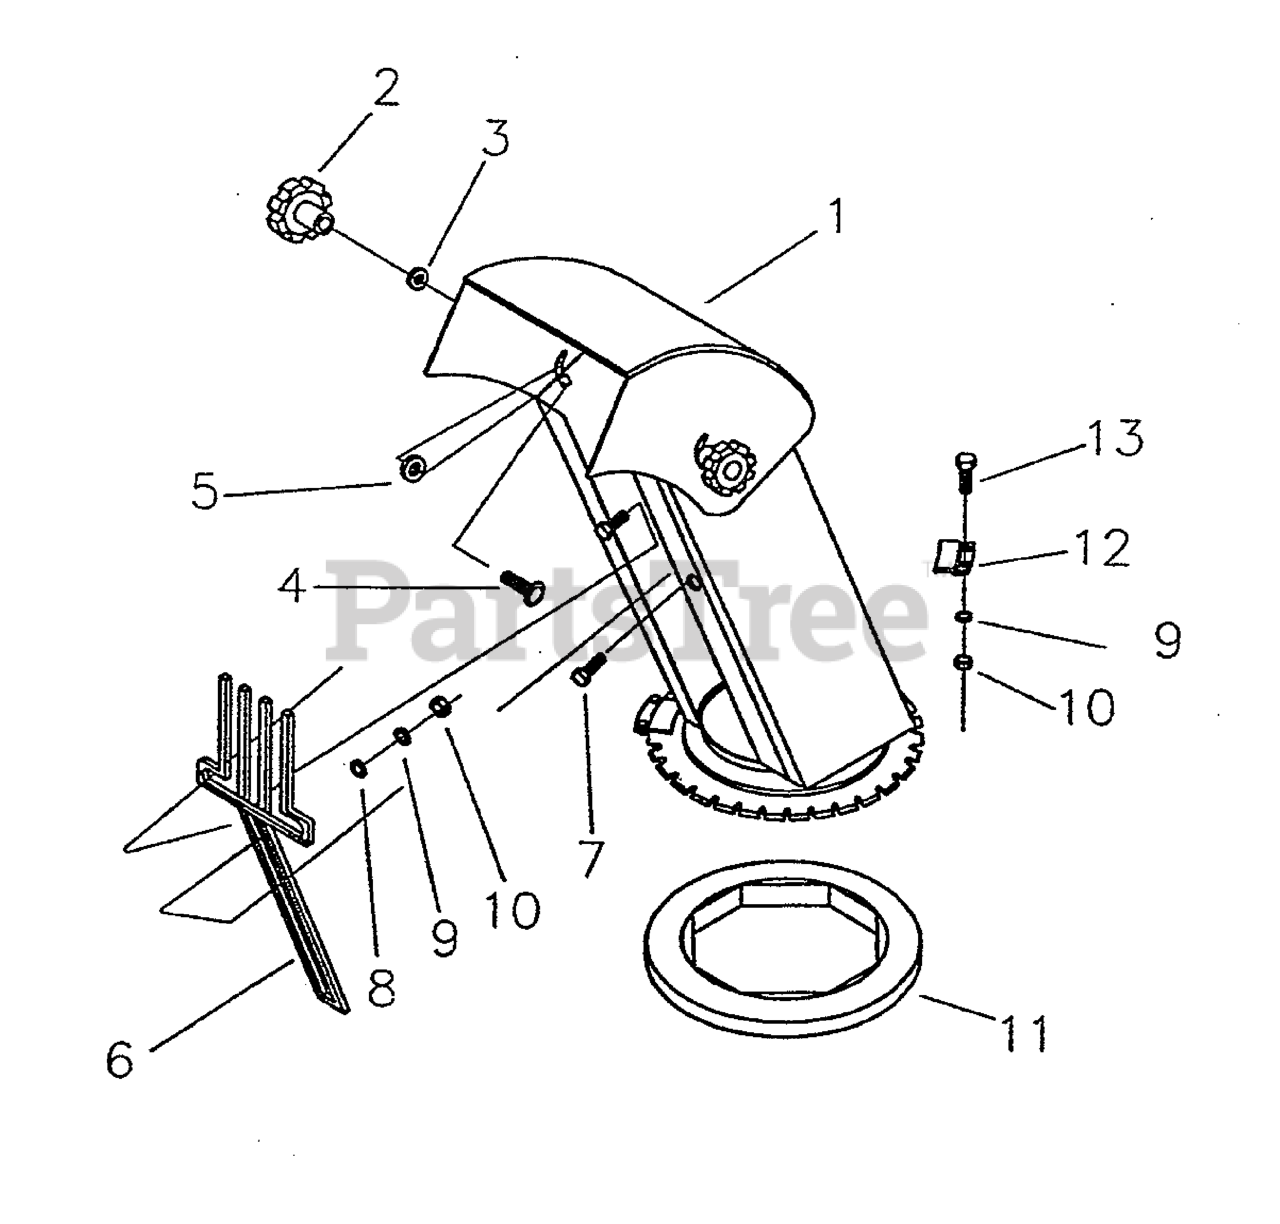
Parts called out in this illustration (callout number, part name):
1	Chute, Base and Knobs with Decals
2	Knob 5/16" NC
3	Nylon Flat Washer 11/32" Diameter Hole
5	Nylon Flat Washer 7/16" Diameter Hole
6	Hand Guard
8	Flat Washer 5/16" Diameter Hole
10	Hex Nut 1/4" NC
11	Nylon Ring
12	Retaining Plate
